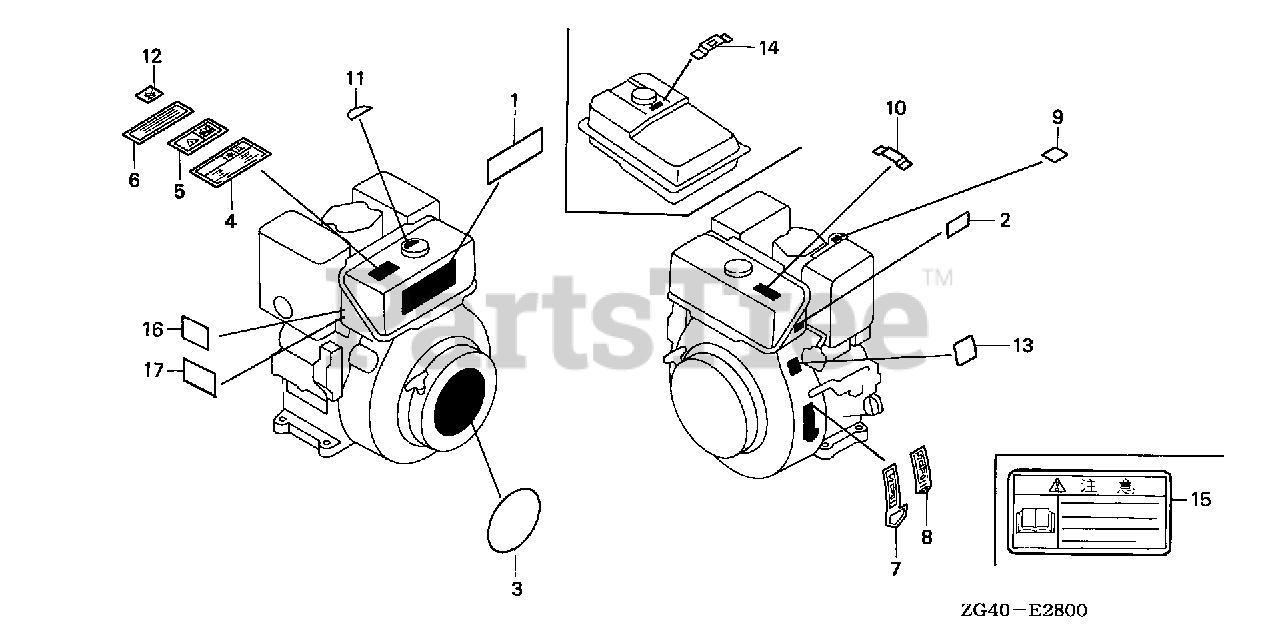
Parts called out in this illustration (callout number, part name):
1	EMBLEM (GD320)
3	PLATE, EMBLEM
4	LABEL, CAUTION (ENGLISH)(FRENCH)(GERMAN) (SPANISH)
7	MARK, THROTTLE (ENGLISH)
10	MARK, FUEL (EXTERNAL)
11	MARK, USE FUEL (ENGLISH)
13	MARK, OIL CAUTION (ENGLISH)
